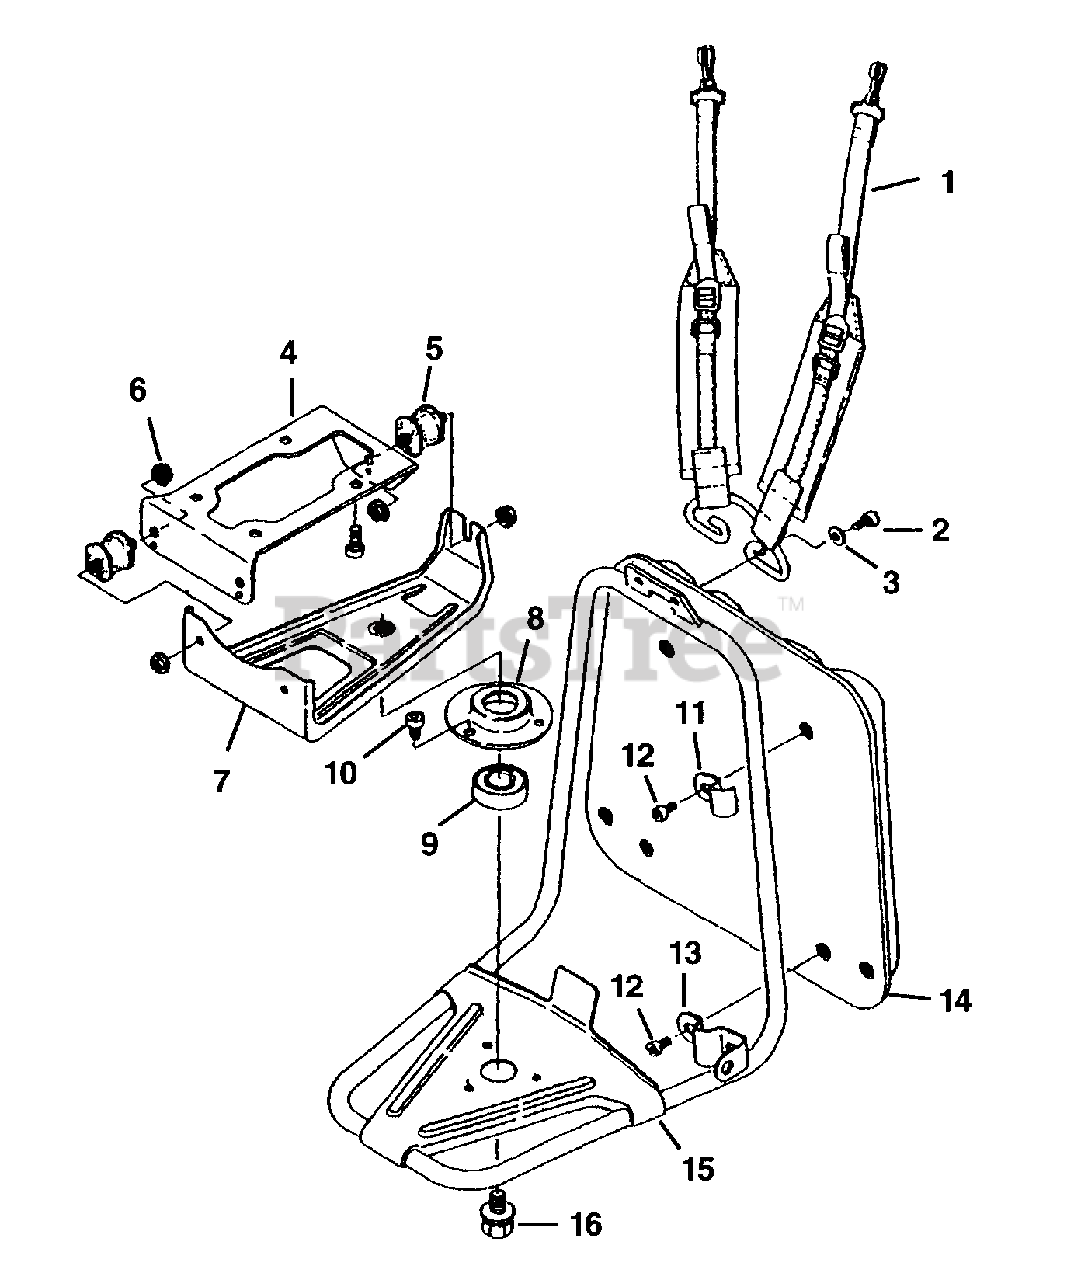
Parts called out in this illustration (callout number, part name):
2	TORX BOLT M6 X 12
3	PLAIN WASHER 6
4	ENGINE STAY
5	AV RUBBER
6	F-NUT M6
7	ENGINE BASE
8	BEARING HOLDER
9	BALL BEARING #6202ZZ
10	TORX SCREW M6 X 10
11	PAD RETAINER (B)
12	TORX BOLT M5 X 10
13	PAD RETAINER
16	BOLT (3) M10 X 20
